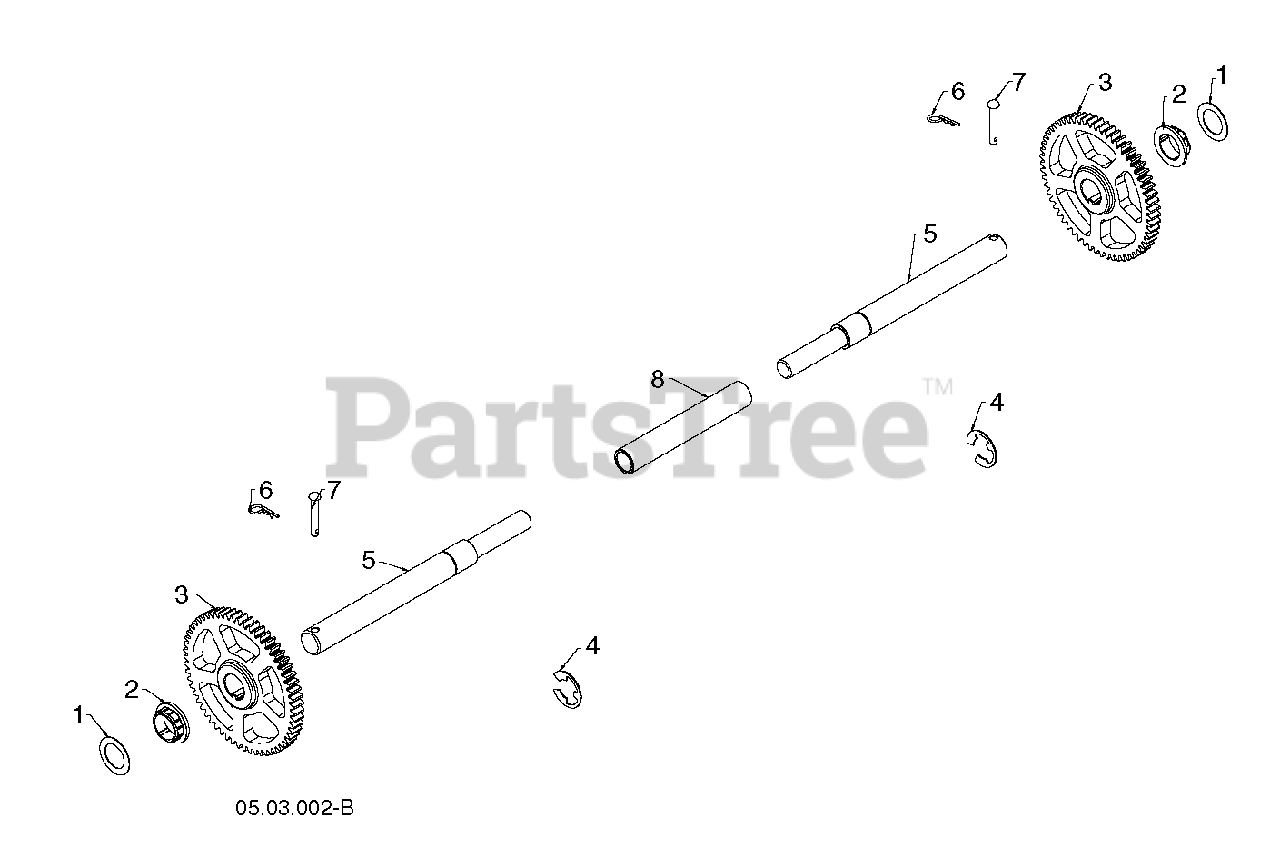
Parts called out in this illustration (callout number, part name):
1	WASHER 1.00
2	Hex Shaft Bushing
3	GEAR.59T
4	E RING HYT
5	AXLE AXLE, SPLIT SHAFT Ã 1.00
8	SLEEVE SLEEVE, AXLE SLEEVE
